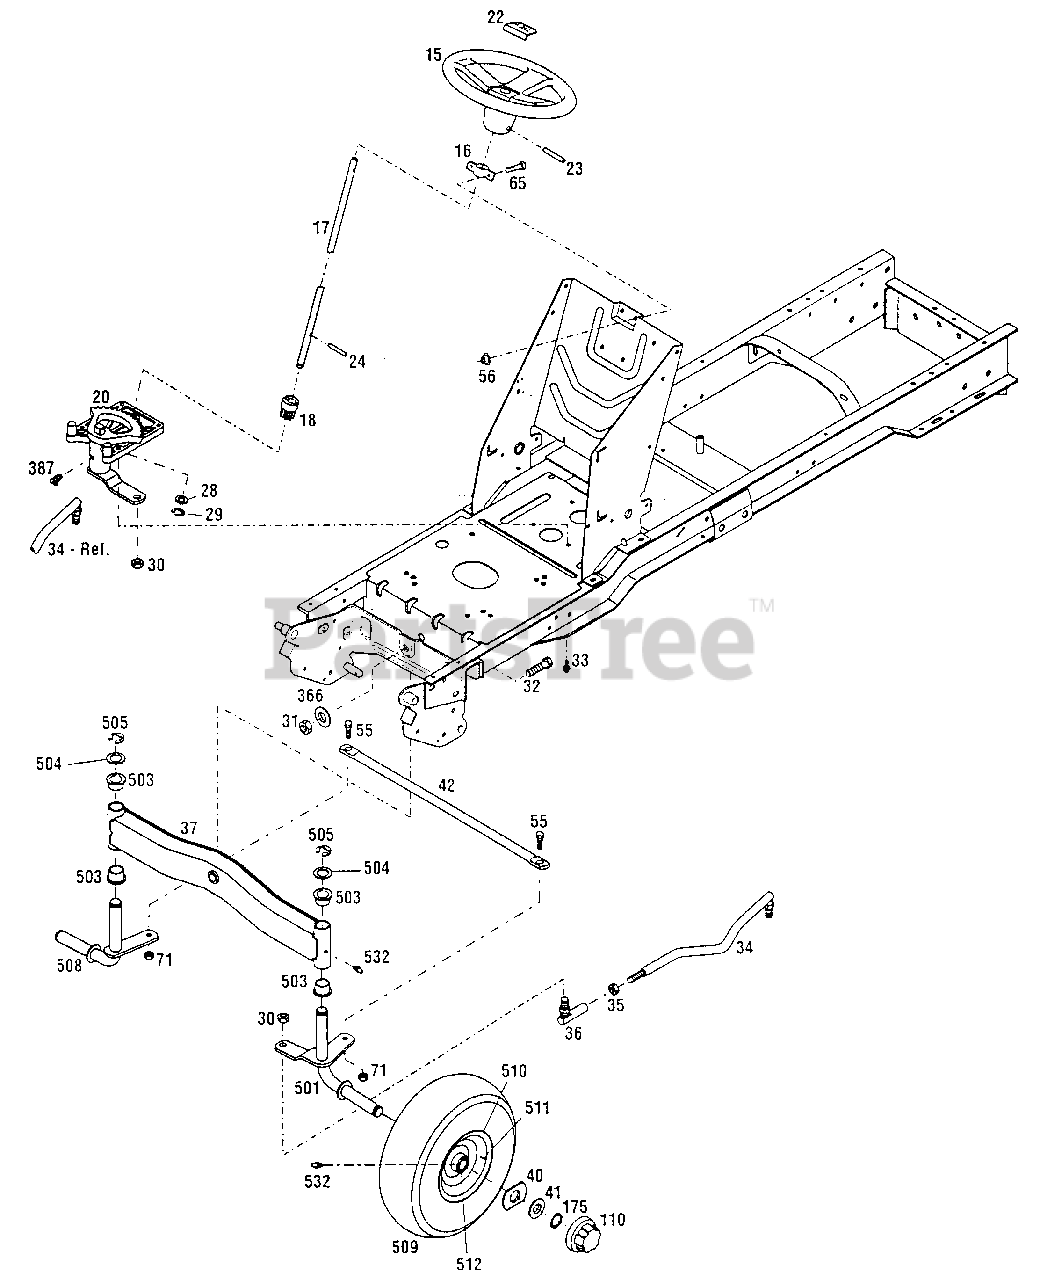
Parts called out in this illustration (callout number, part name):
15	Premium Steering Wheel
16	Bearing
17	Steering Shaft
18	Pinion Gear
20	Steering Gear Assembly
22	Steering Wheel Cap
23	Roll Pin, 1/4 x 2
24	Drive Pin, 1/4 x 1-1/4
28	Special Washer, 5/8 x 1
29	Retaining Ring, 5/8
30	Locking Jam Nut, 1/2-20
31	Top Locknut, 5/8-11
32	Hex Head Screw, 5/8-11 x 2 3/4
33	Flange Lock Screw, 5/16-18 x 3/4
34	Drag Link
35	Hex Jam Nut, 1/4-20
36	Ball Joint
40	Special Washer, 3/4 x 2-1/2
41	Special Washer, 3/4 x 1-3/8
55	Shoulder Bolt, 3/8-24
56	Flange Nut, 1/4-20
65	Flange Screw 1/4-20 x 5/8
71	Self-Locking Nut, 3/8-24
110	Hub Cap
175	Retaining Ring
366	Flat Washer, 5/8
387	Grease Fitting, 90°.
501	Left Spindle Assembly
503	Axle Bushing
504	Special Washer, 3/4
505	Retaining Ring, External
508	Right Spindle Assembly
509	Tire, 15 x 6.00, 6 RS
510	Rim Assembly
511	Valve Stem
512	Wheel Bearing
532	Grease Fitting
